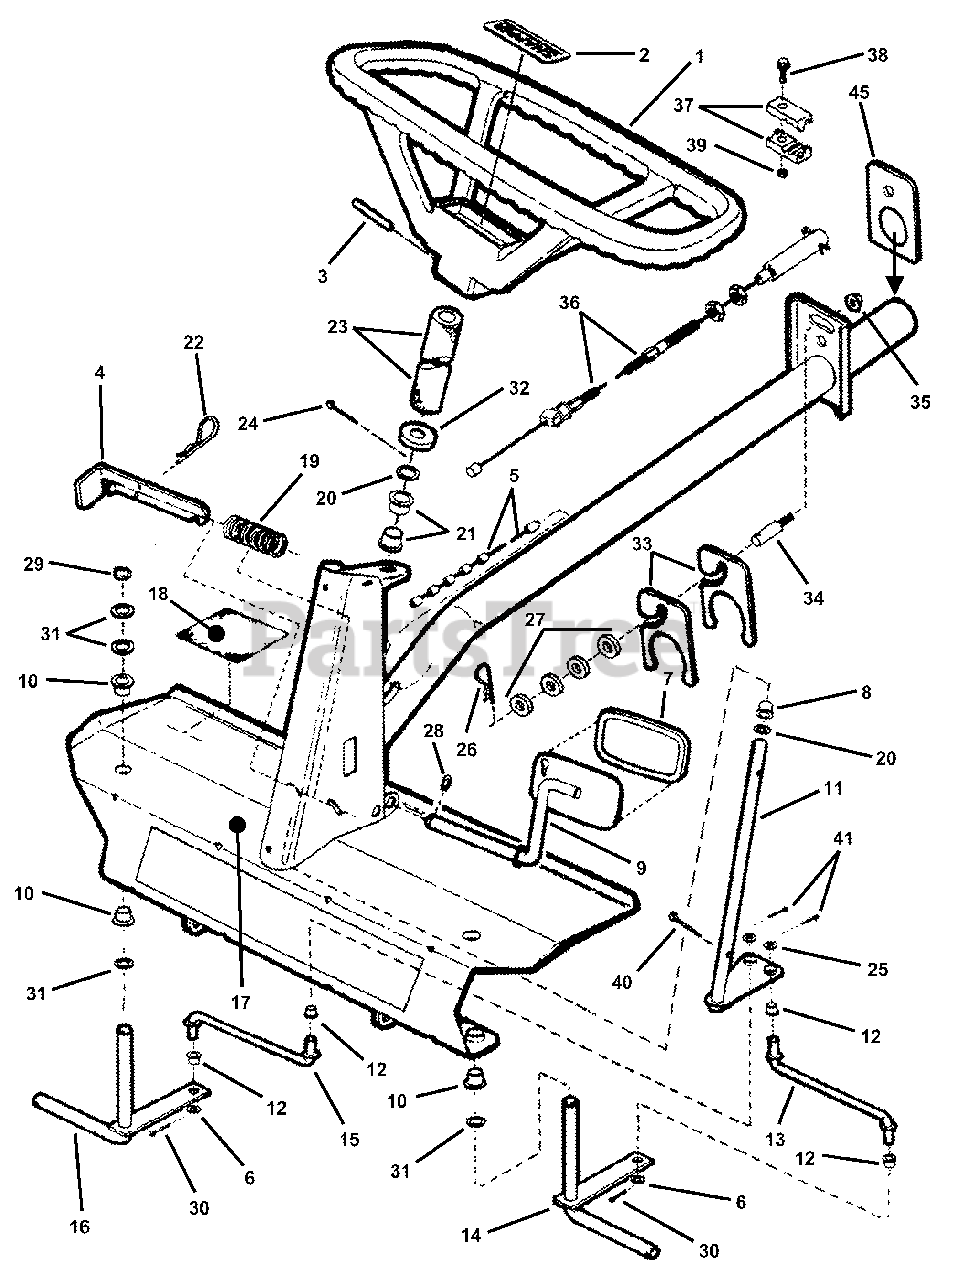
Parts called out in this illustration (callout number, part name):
1	STEERING WHEEL (for 5/8" shaft)
2	LOGO, Steering Wheel
3	PIN, 1/4 x 1-1/2" Roll
4	LATCH, Parking Brake
5	CABLE, Clutch/Brake(54.32")
6	WASHER, 3/8" Flat
7	PAD, Clutch/Brake Pedal
8	BUSHING, Nylon
9	PEDAL, Clutch/Brake (weldment)
10	BEARING, Nylon
11	SHAFT, Steering (weldment)
12	BUSHING, Tie-Rod
13	TIE-ROD, Left Hand (7.41" long)
14	KING-PIN Weldment, Left Hand
15	TIE-ROD, R. H. (7.41" long)
16	KING-PIN, Weldment Right Hand
17	WELDMENT, Front Axle, Narrow
18	FOOT PAD, Short
19	SPRING, Parking Brake
20	WASHER, 21/32 I. Dia.
21	BUSHING, Nylon
22	PIN, Hair
23	FOAM COVER, Steering Shaft
24	PIN, 3/16 x 1" Cotter
25	WASHER, 3/8" Flat
26	PIN, Hair (.125" Dia. Wire)
27	SPACER, 1/2"
28	RING, 1/2" External Retaining (Heavy Duty)
29	RING, 3/4" Ext. Retaining
30	PIN, 1/8 x 3/4" Cotter
31	WASHER, 5/8 Flat
32	COVER, Steering Shaft
33	SPACER, Pivot
34	STUD, Shoulder (3/8-24 Thread)
35	NUT, 3/8-24 Hex Nyloc
36	CABLE, Brake (29" long)
37	CONNECTOR, Cable
38	SCREW, 1/4-20 x 3/4", Gr. 5
39	NUT, 1/4-20 Hex Center Lock
40	PIN, 3/16" x 1-1/2" Cotter
41	PIN, 5/32" x 1" Cotter
45	PLATE, Thrust
